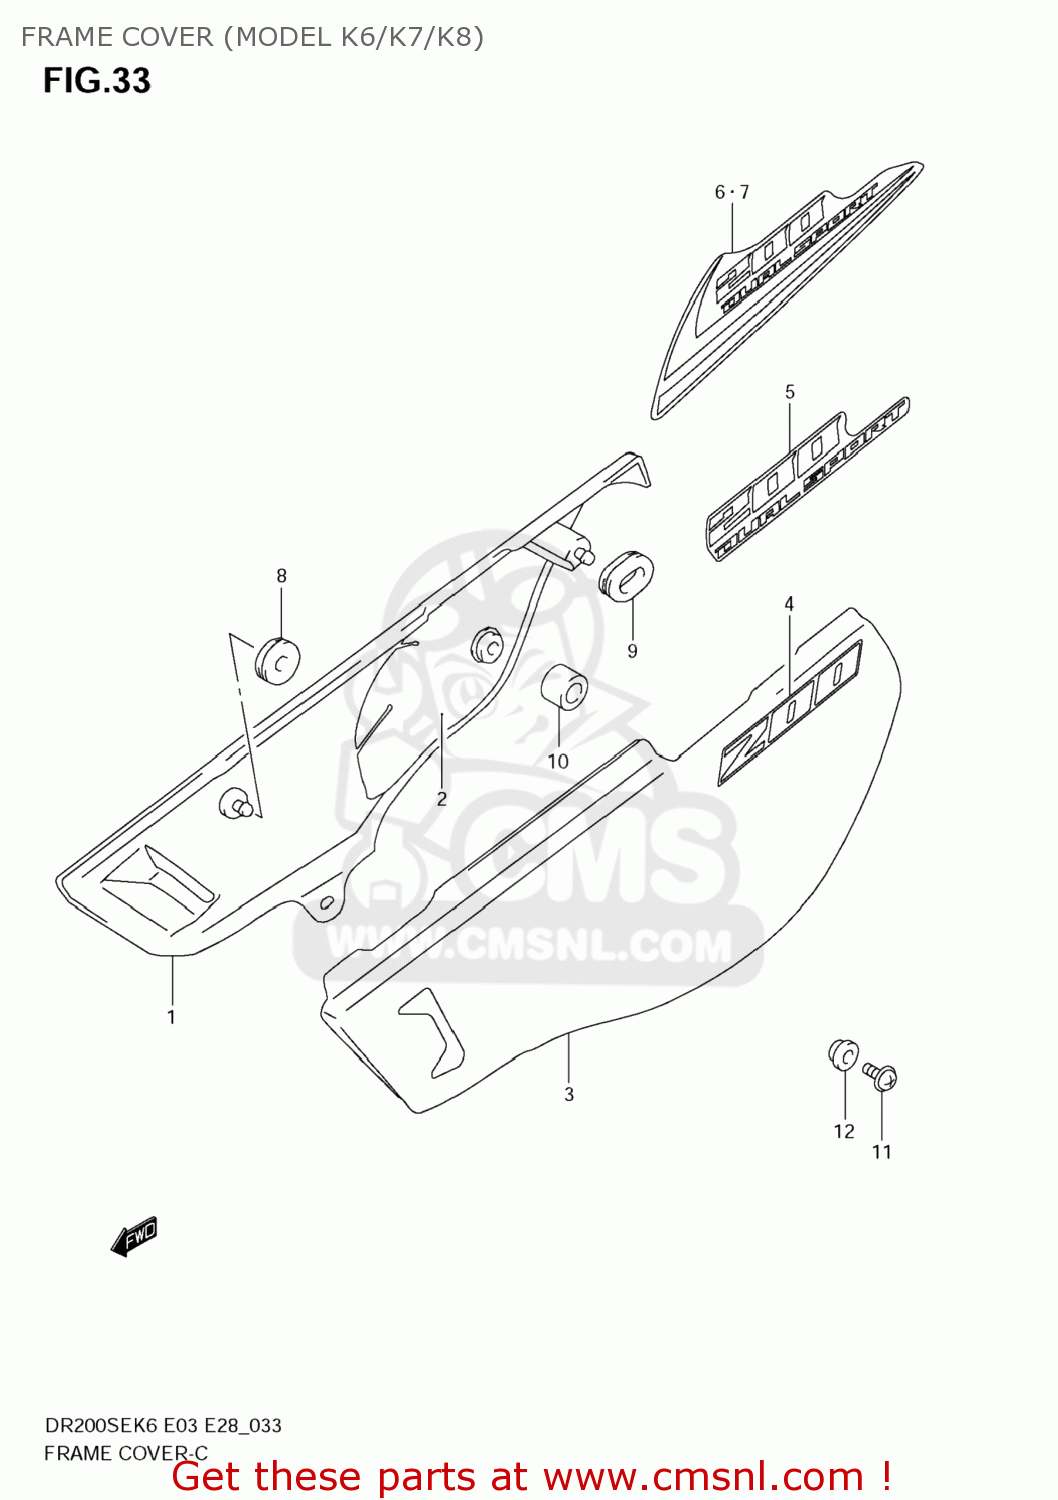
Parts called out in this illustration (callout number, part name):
1	COVER,FRAME,R(WHITE)
2	SHIELD,FRAME COVER,R
3	COVER,FRAME,L(WHITE)
4	EMBLEM,FRAME COVER
5	EMBLEM,FRAME COVER
6	TAPE,FRAME COVER,R
7	TAPE,FRAME COVER,L
8	CUSHION
9	CUSHION
10	CUSHION
11	SCREW(6X16)
12	WASHER
